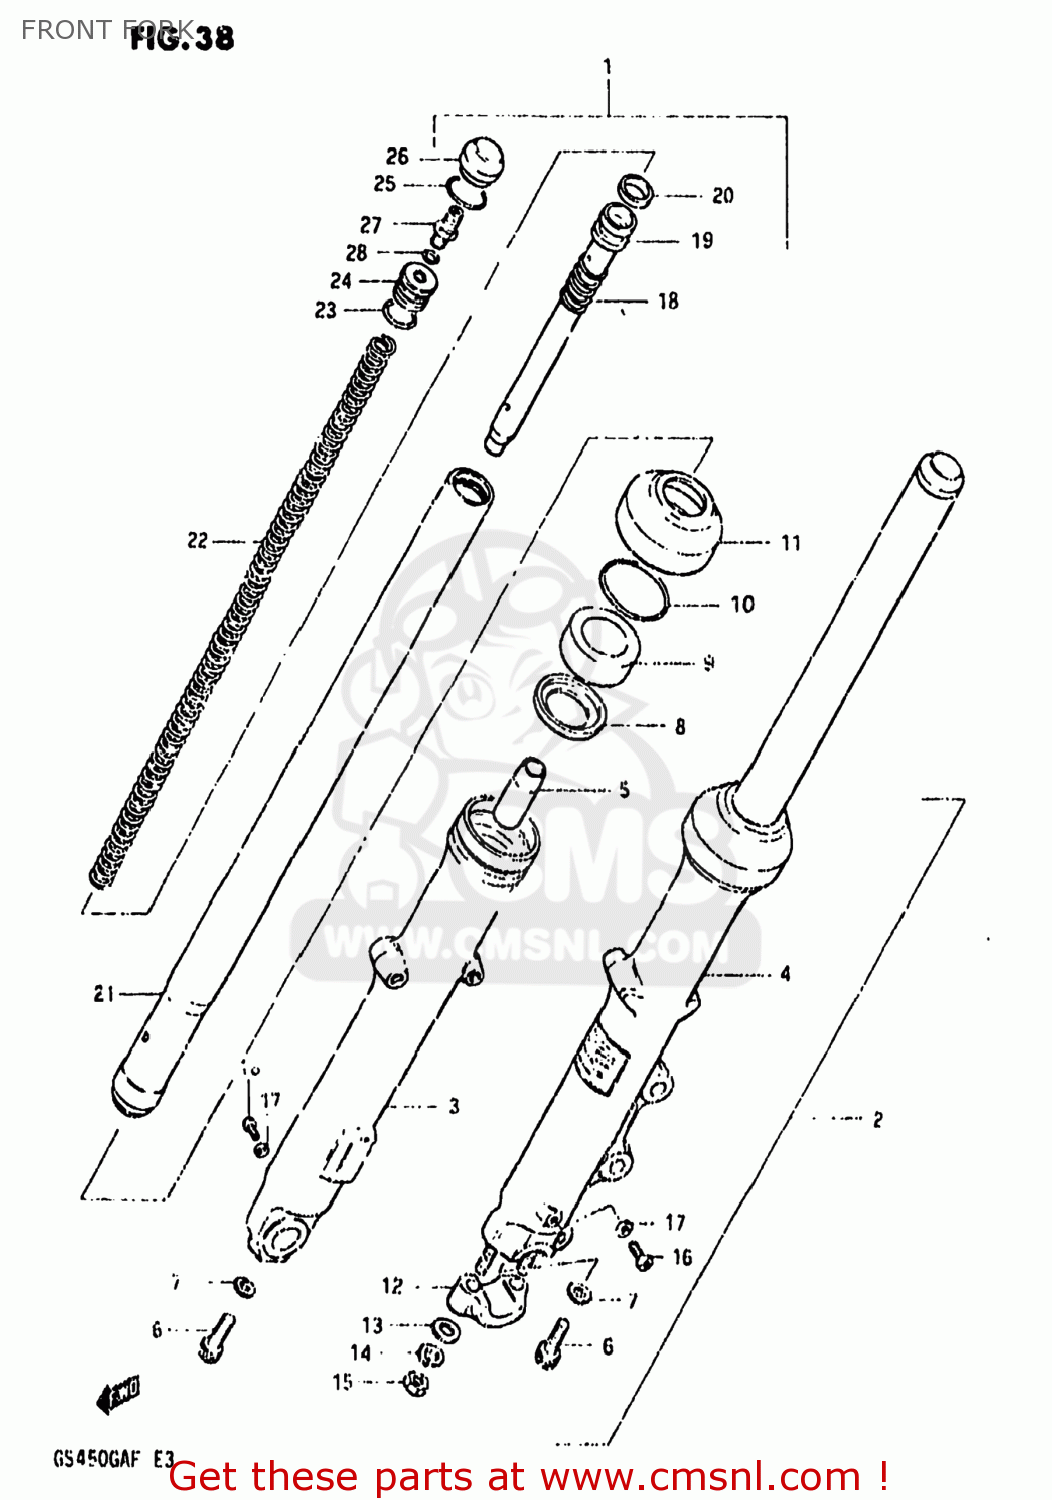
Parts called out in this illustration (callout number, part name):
1	DAMPER ASSEMBLY,RIGHT
2	DAMPER ASSEMBLY,LEFT
3	TUBE,FORK,OUTER,RIGHT
4	TUBE,FORK,OUTER,RIGHT
5	PIECE,OIL LOCK
6	BOLT(8X27)
7	GASKET (NAS)
8	SPACER,OIL SEAL
9	OIL SEAL,FRONT FORK
10	OIL SEAL,FRONT FORK
11	DUST SEAL
12	HOLDER,AXLE
13	WASHER
14	LOCK WASHER
15	NUT
16	SCREW 4X6
17	GASKET (NAS)
18	SPRING,REBOUND
19	CYLINDER,FRONT FORK
20	RING,PISTON
21	TUBE,FORK,INNER
22	SPRING
23	O RING
24	SEAT,SPRING
25	RING,STOPPER
26	CAP,FRONT FORK
27	VALVE,AIR
28	O-RING (D:3.8 ID:19)
